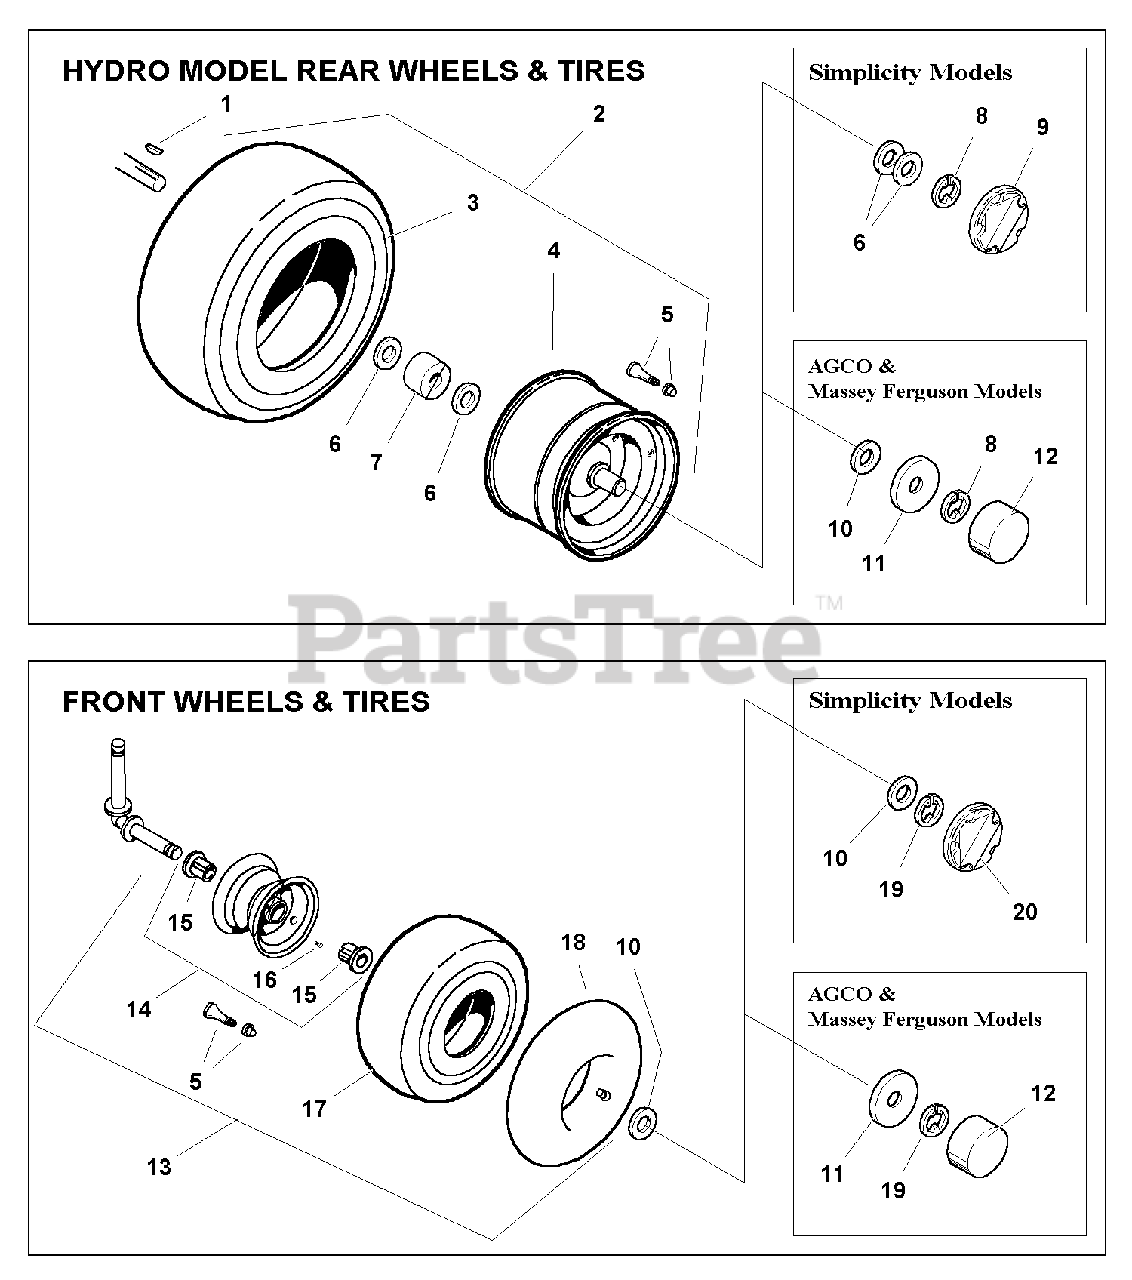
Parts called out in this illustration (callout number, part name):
1	KEY
2	REAR WHEEL & TIRE ASSEMBLY, 20x8.00-8 (Includes Ref. Nos. 3, 4, & 5)
3	TIRE, 20 x 8.00-8"
4	WHEEL, Metallic Gray, 8", Rear
5	VALVE STEM & CAP
6	WASHER, 3/4 (Qty. 8 used on Simplicity models, 4 on AGCO & Massey Ferguson Models)
9	HUB CAP, 7-3/4" Black, Rear Scalloped (Simplicity Models)
10	WASHER , 3/4
11	RETAINER, Cap (AGCO & Massey Ferguson Models)
12	CAP, Axle (AGCO & Massey Ferguson Models)
13	FRONT WHEEL & TIRE ASSEMBLY, 15 x 6.50-6 (Includes Ref. Nos. 5, 14, 15, 16 & 17)
14	WHEEL ASSEMBLY, Metallic Gray, 6", Front (Includes Ref. Nos.15 & 16)
15	BEARING
16	FITTING, Grease
17	TIRE, 15 x 6.50-6"
18	TUBE, Tire 6", Front
19	KLIPRING, 3/4
20	HUB CAP, 5-3/4, Black, Front Scalloped (Simplicity Models)
